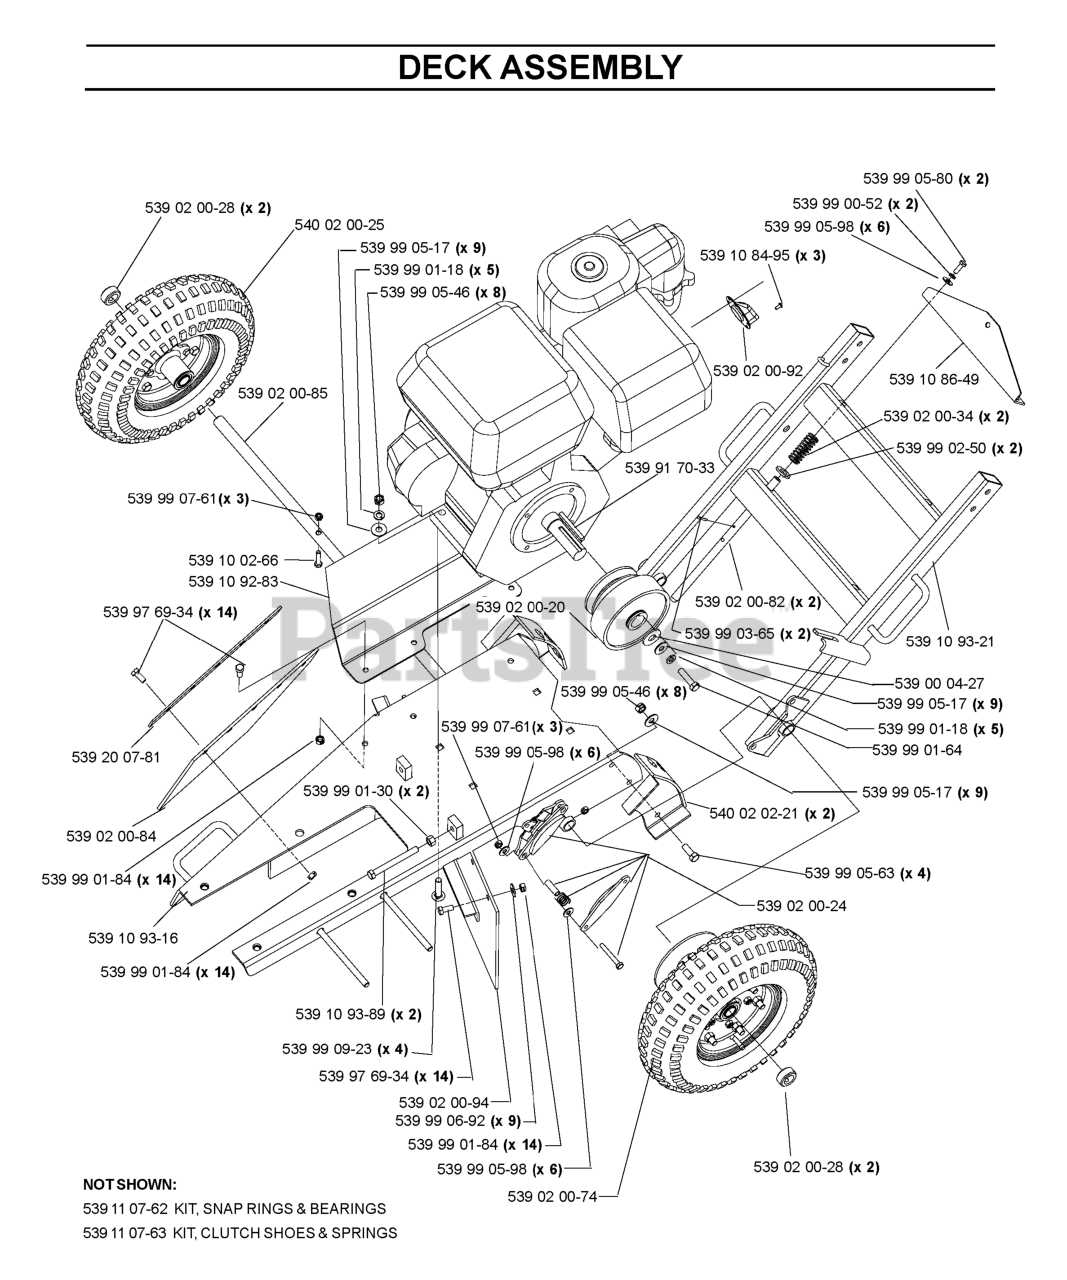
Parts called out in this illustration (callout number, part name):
1	KIT, HANDLE ASSY
2	CLUTCH CABLE
4	BOLT KIT
5	BELT KEEPER KIT
6	BELT GUARD KIT ORN
7	DEPTH LEVER ASSY
8	IDLER ASSY KIT
9	PULLEY
10	MTG ARM, IDLER PULLEY
11	SPRING
12	DEPTH ADJUSTMENT KNOB
13	3-PRONGED LOCK DEPTH
14	ROTOR GUARD
15	WHEEL
16	BOLT KIT
17	KIT, WHEEL
18	KIT, WHEEL, RIGHT REAR
19	LIFT ARM ROD KIT
20	LIFT ARM ASSY OR
21	TORSION SPRING
22	BEARING
23	STAMPING KIT
24	ROTOR CAP
26	STAMPING KIT
27	V-PULLEY
28	BUSHING KIT
29	V-BELT
30	V-BELT
31	V-PULLEY
32	V-PULLEY
33	ENGINE BOLT KIT
35	DEFLECTOR KIT
36	DEFLECTOR, NEOPRENE
37	KIT, HOPPER LID
38	DIAL GAUGE KIT
39	KIT, PUSH-PULL CONTROL
40	SEED HOPPER
41	AGITATOR BAR
44	Kit Decal SD18 Seeder
